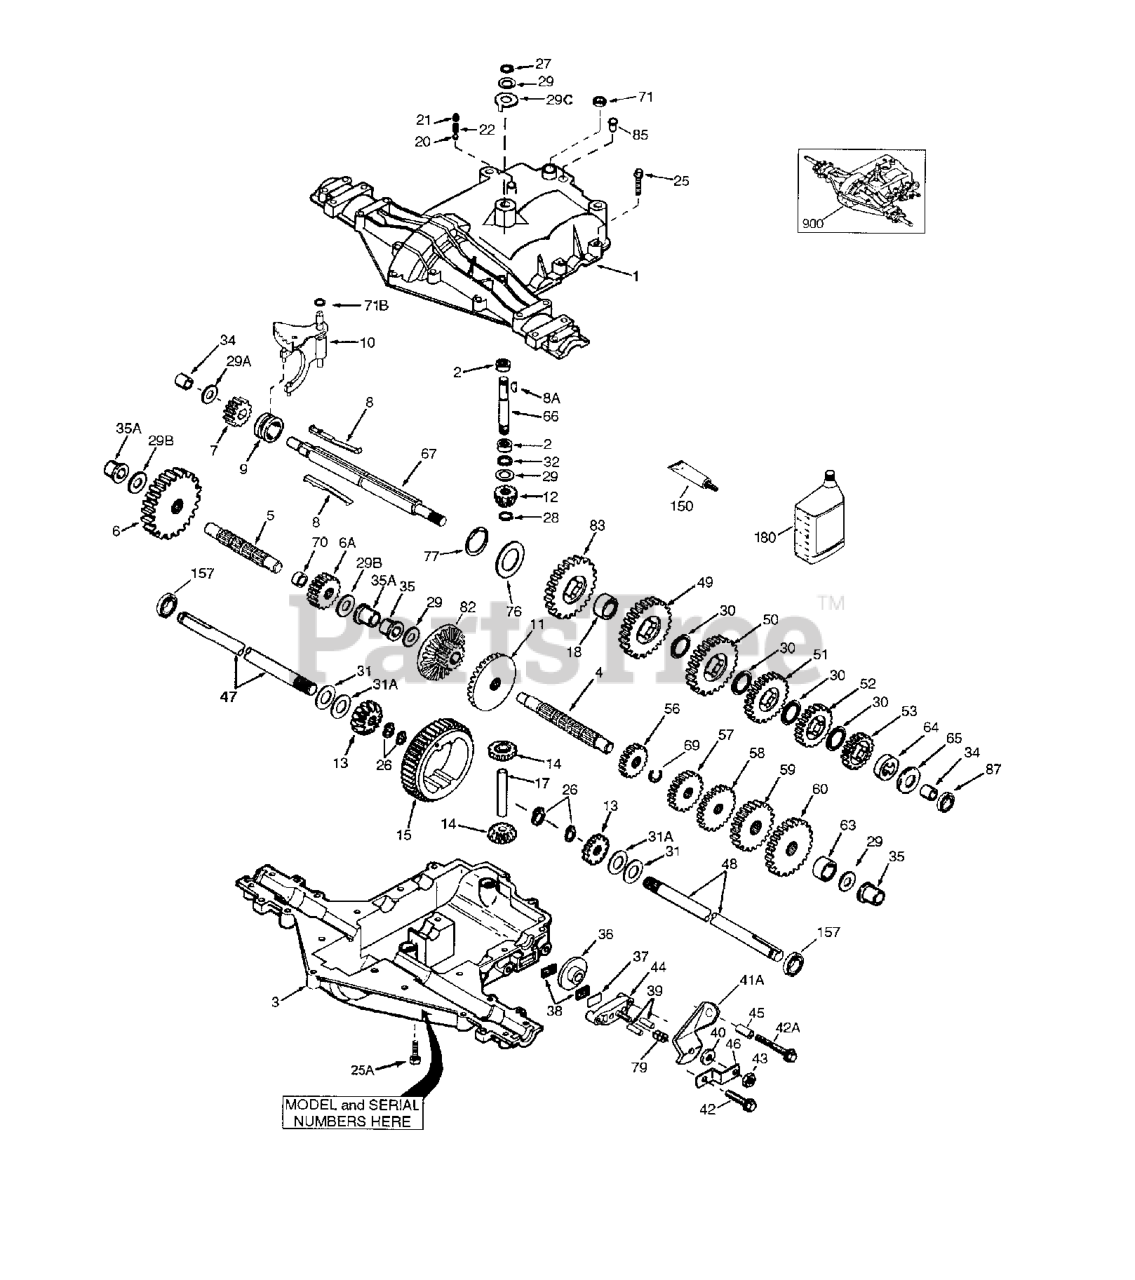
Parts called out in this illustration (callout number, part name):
1	Transaxle Cover
2	Needle Bearing 5/8" ID
3	Transaxle Case
4	Countershaft
5	Output Shaft
6	Spur Gear (38 teeth)
6A	Spur Gear (15 teeth)
7	Spur Gear (11 teeth)
8	Shift Key
8A	Woodruff Key No. 9
9	Collar, Shifter
10	Shift Rod & Fork
11	Bevel Gear (30 teeth)
12	Input Bevel Pinion (13 teeth)
13	Bevel Gear (13 teeth)
14	Bevel Pinion (13 teeth)
15	Ring Gear (43 teeth)
17	Drive Pin
18	Spacer, Neutral
20	Ball, Steel 5/16" diameter
21	Set Screw 3/18-16 x 3/8"
25A	Screw 1/4-20 x 1-3/8"
26	Ring, Retainer (4 Required, Package of 2)
27	Retaining Ring
28	Ring, Retaining
29	Washer, Thrust
29B	Thrust Washer (.762 ID)
29C	Anti-Rotation Washer .632
30	Washer, Thrust
31	Washer (.056 wide)
31A	Flat Washer (.062 wide)
32	Oil Seal 5/8"
34	Bushing 9/16"
35	Flanged Bushing 5/8" ID
35A	Flanged Bushing 3/4"
36	Brake Disk
37	Plate, Brake pad
38	Brake Pad (pkg of 2)
39	Pin, Dowel
40	Washer, Flat
41A	Lever, Brake
42	Screw, 1 /4-20 x 1-1 /4"
42A	Screw, 1 /4-20 x 2-1 /4"
43	Lock Nut 5/16-24
44	Holder, Brake pad
45	Spacer (1/2" OD)
46	Bracket, Brake lever
47	Axle (11-15/16" long)
48	Axle (16-1/2" long)
49	Spur Gear (29 teeth)
50	Spur Gear (23 teeth)
51	Spur Gear (19 teeth)
52	Spur Gear (16 teeth)
53	Spur Gear (15 teeth)
56	Spur Gear (11 teeth)
57	Spur Gear (17 teeth)
58	Spur Gear (21 teeth)
59	Spur Gear (24 teeth)
60	Spur Gear (25 teeth)
63	Countershaft Spacer (1-1/8" x 3/8")
64	Brake Shaft Spacer (1-3/8" x 3/8")
66	Input Shaft
67	Shifter & Brake Shaft
69	Retaining Ring
70	Spacer .890
71	Seal, Square Cut
71B	"O" Ring
76	Washer, Thrust
77	Ring, Retaining, Inverted (Package of 2)
79	Piston Assembly
82	Bevel & Spur Gear (30 & 13 teeth)
83	Spur Gear (27 teeth)
85	Oil Fill Plug
87	Oil Seal 9/16"
150	Liquid Gasket RTV Silicone
157	Oil Seal 3/4"
180	Gear Oil 80W90
